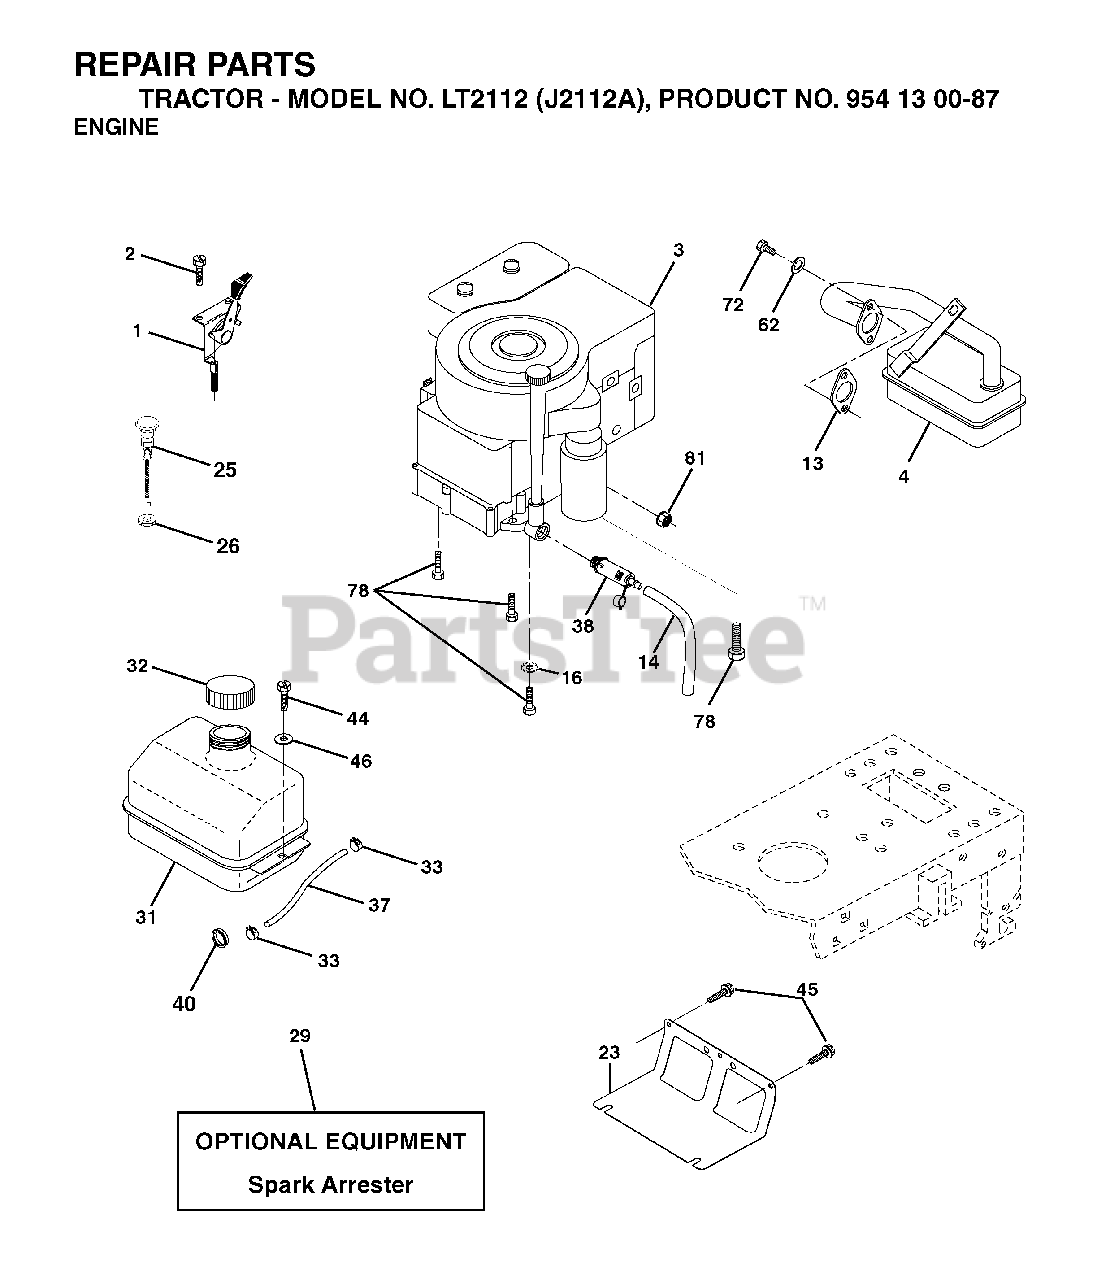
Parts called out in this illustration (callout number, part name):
1	CONTROL TH/CH FLAG
2	SCREW
13	REPL BY 532 27 22-93
14	TUBE, DRAIN OIL ASM.
16	LOCKWASHER
23	SHEILD.BROWNING.DBR.GUARD
26	NUT KEPS 3/8 - 24 UNF
29	ARRESTER SPARK (OPTIONAL)
32	FUEL CAP
33	HOSE CLAMP
37	LINE.FUEL.20
38	PLUG DRAIN OIL EASY
40	GROMMET T
44	SCREW HEXWSHR 1/4-20X3/4
45	SCREW, 3/8-16X3/4
62	LOCKWASHER
72	SCREW
78	SCREW.3/8-16
81	NUT
